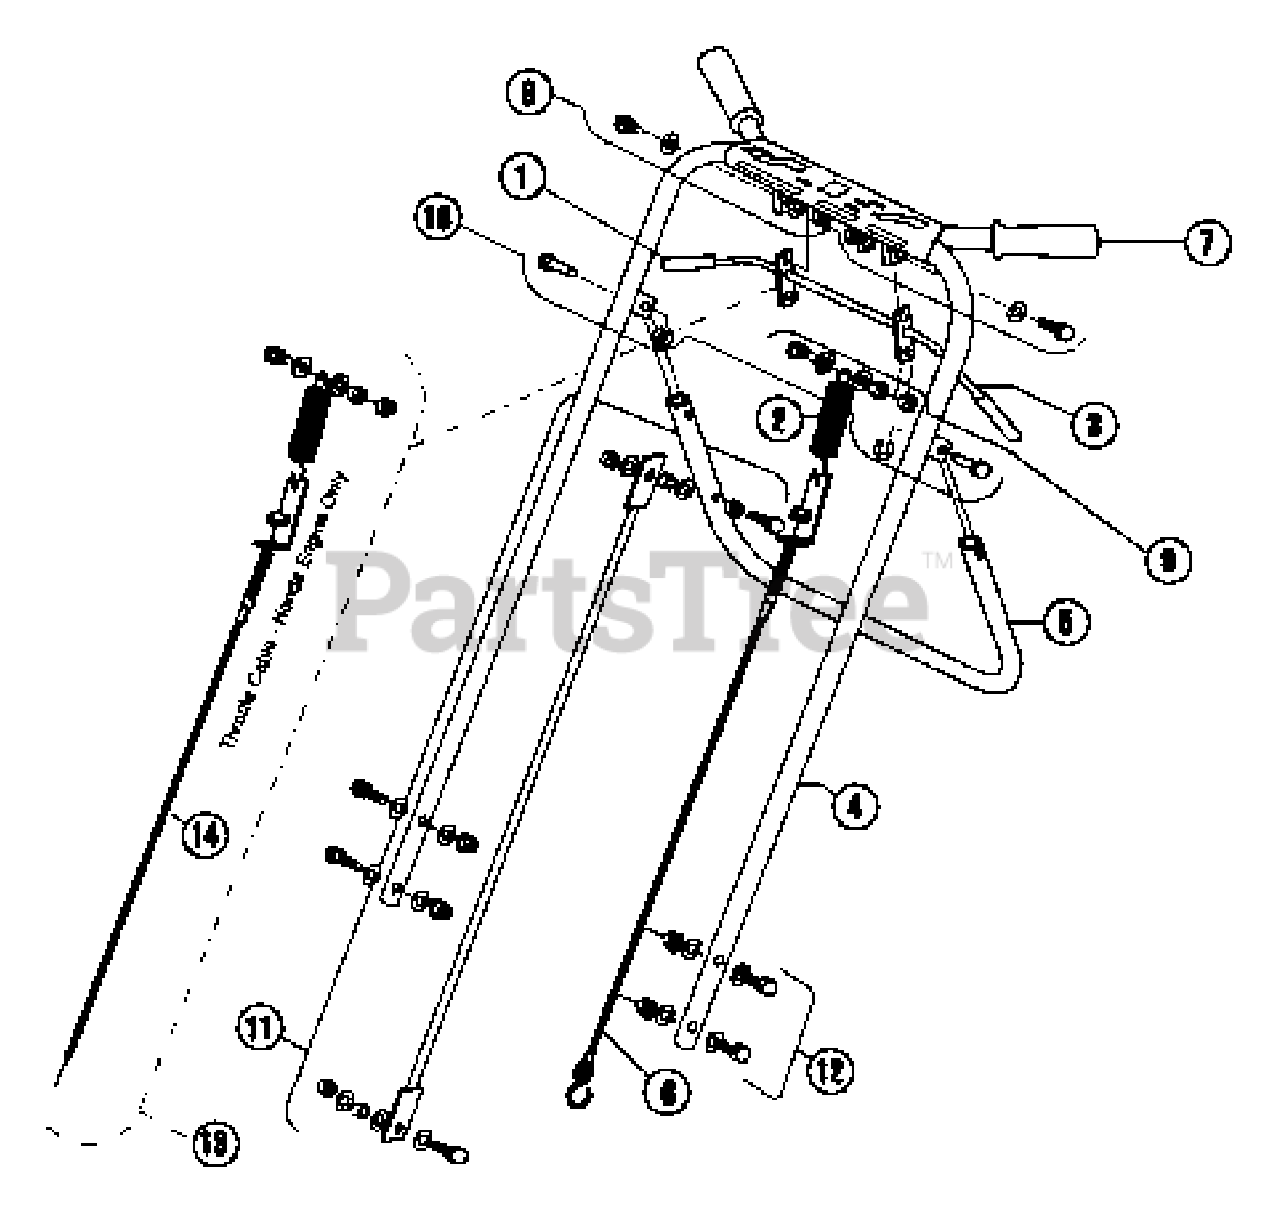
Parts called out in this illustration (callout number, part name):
1	Grip, clutch
2	Spring, clutch
3	Clutch control, with grips
3	Clutch/throttle control, Honda engines only
4	Handle with grips
5	Handle, control, rear wheel
6	Clutch cable
7	Grips, pair
8	Fastener kit, clutch control to handle
9	Clutch cable kit
10	Pin kit, rear wheel control handle
11	Rear wheel control rod kit
12	Fastener kit, handle
13	Throttle cable kit - Honda engine only
14	Throttle cable
